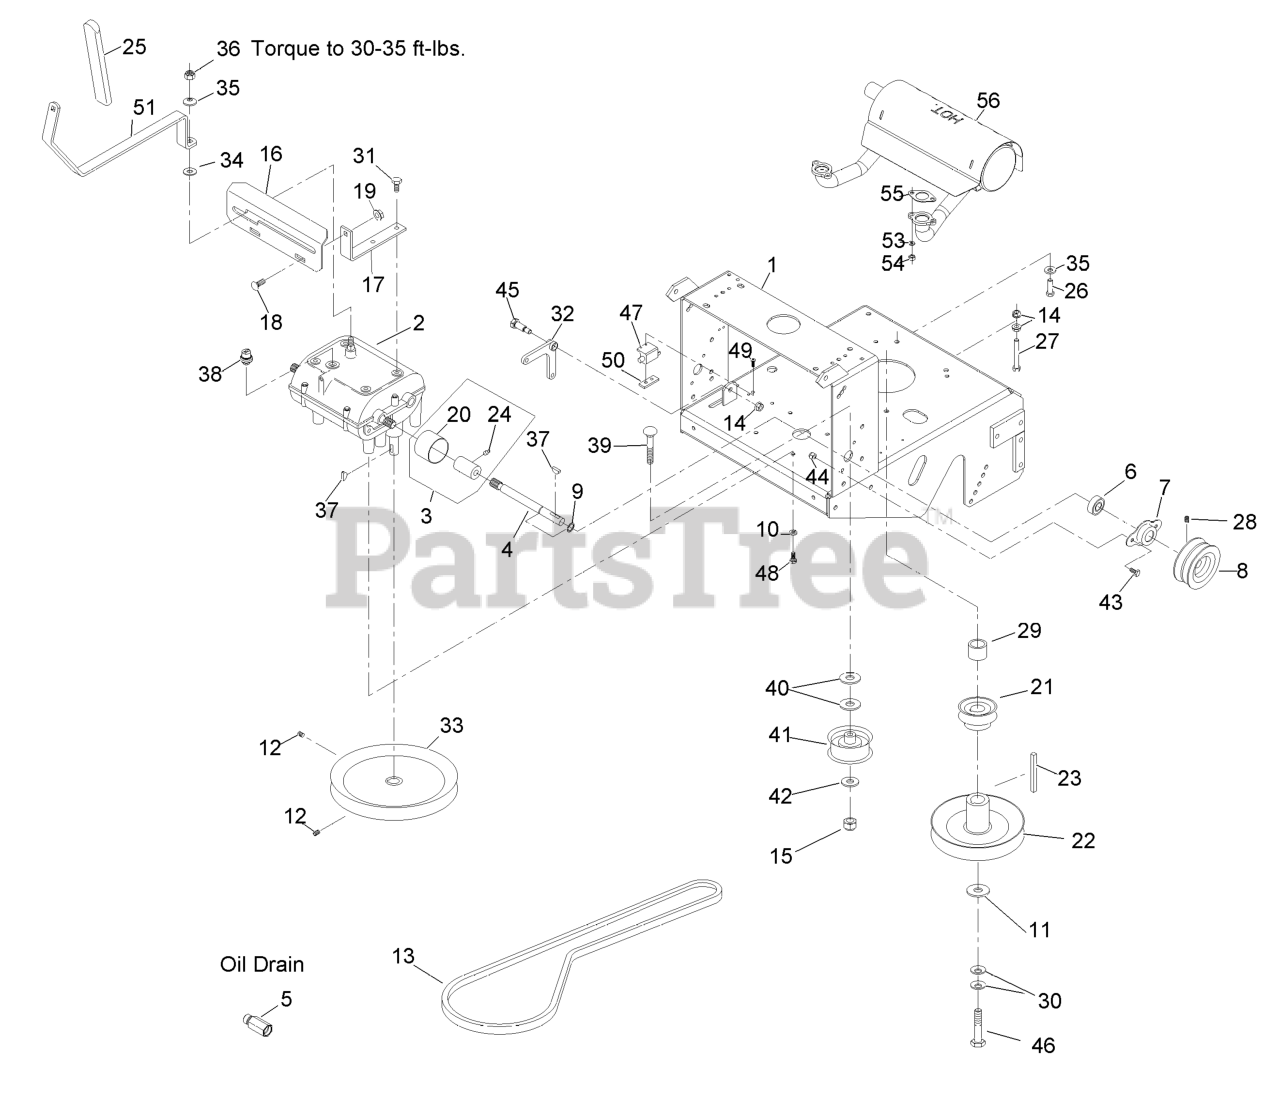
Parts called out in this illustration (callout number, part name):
3	ASM,COUPLER/ZERK
4	SHAFT-TRANSMISSION
5	ADAPTER
6	BEARING-SHAFT
7	FLANGE-OUTPUT
8	SHEAVE-TRANSMISSION
9	RING-RETAINING
10	WASHER-LOCK
11	WASHER
13	BELT,TRANS DRIVE
14	NUT-HHF, WHIZ
15	NUT-LOCK, NI
16	PLATE,SHIFTER W/DECAL
17	BRACKET-PLATE, SHIFT
18	BOLT-CARR
19	NUT-HF
20	GUARD-COUPLER
21	SHEAVE-TRANSMISSION
23	KEY
24	FITTING-GREASE
25	GRIP,FOAM
26	SCREW-HH
27	SCREW-HH
29	SPACER-CLUTCH
30	WASHER-SPRING
31	SCREW-HWH, THREAD CUT
32	BELLCRANK
33	SHEAVE-TRANSMISSION
34	WASHER
35	WASHER-BELLEVILLE
36	NUT-LOCK
37	KEY-WOODRUFF
38	SWITCH-START, NEUTRAL
39	SCREW-HH
40	WASHER-FLAT
42	WASHER-FLAT
43	SCREW-HH
44	NUT-LOCK, NI
45	BOLT-SHOULDER
47	SWITCH-OPEN, NORMALLY
48	SCREW-HH
49	SCREW-PPH
50	PLATE-TAPPED
51	ASM,SHIFT LEVER
53	WASHER-LOCK
54	NUT
55	GASKET-EXHAUST
56	MUFFLER-HORIZONTAL, OFFSE
